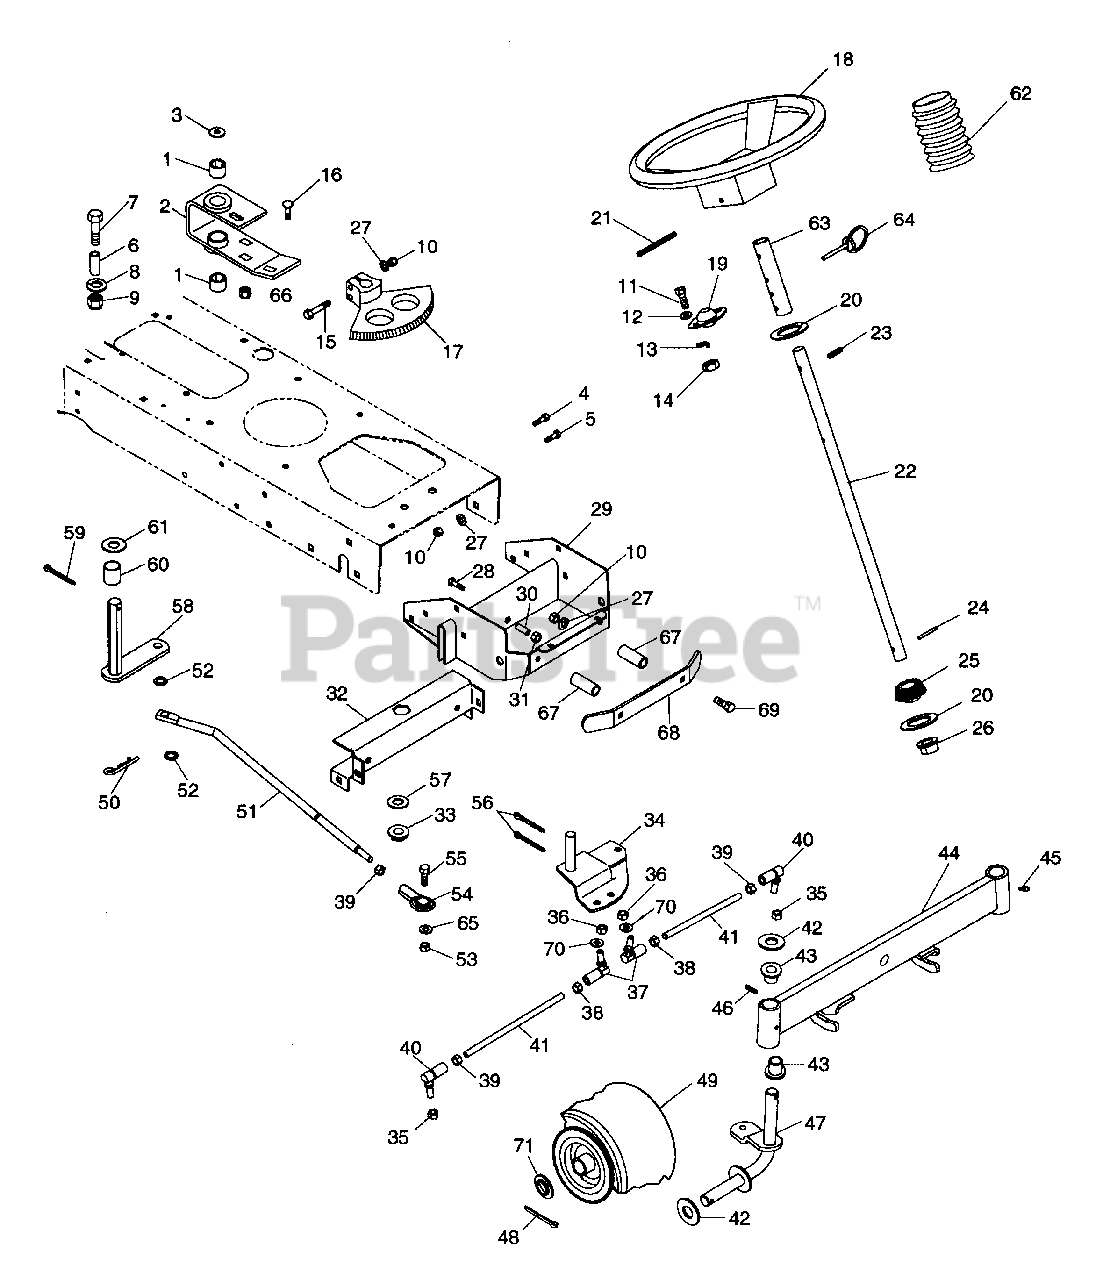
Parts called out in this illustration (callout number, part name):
1	BSHG-SLV .750X1.000X.750 HX SB
2	STEERING BRACKET
3	WSHR-FL-STL .880X1.250X.062
4	BLT-RDHDSQSHNK .38-16X1.00 PL
5	BLT-RDHDSQNK .38-16X.75 SHT PL
6	SPACER .344X.500X.875
7	BLT-HEX .31-18X1.50 PL GR2
8	WSHR-LK .312X.097 PL HVY
9	NUT-HEX .312-18
10	NUT-HEX .375-16
11	BLT-HEX .31-18X.75 PL GR5
12	WSHR-FL-STL.312X.734X.065PL
13	WSHR-LK .312X.097 PL HVY
14	NUT-HEX .312-18
15	BLT-HEX .31-18X1.75 PL GR2
16	BLT-RDHDSQSHNK .38-16X1.00 PL
17	STEERING BEVEL GEAR
18	STEERING WHEEL 13"
19	BRG-FLG .751X2 HOLESX.81
20	WSHR-FL-STL .754X1.125X.062 PL
21	PIN-ROLL .250X1.75
22	STEERING COLUMN
23	PIN-ROLL .188X1.13
24	PIN .249X1.125 DRIV-LOK SP
25	PINION GEAR-STEERING
26	BSHG-FLG .750X1.093X.625X1.375
27	WSHR-LK .375X.094 MED PL
28	BLT-HEX .50-13X1.50 PL GR5
29	FRONT AXLE SUPPORT
30	SPACER .531X.748X.524
31	NUT-LK-CROWN .50-13 GR C PL
32	STEERING PIVOT CHANNEL
33	FLANGE BUSHING
34	STEERING PIVOT
35	NUT-LK .375-24 PL
36	NUT-LK-CTR .375-24
37	BALL JOINT-LH
38	NUT L.H. THD .375-24 PL
39	NUT .375-24 PL
40	BALL JOINT-RH
41	TIE ROD
42	WSHR-FL-STL .755X1.375X.062 PL
43	BSHG-FLG .750X1.000X.750X1.250
44	FRONT AXLE
45	SPIN DRIVE ZERK FITTING
46	PIN-ROLL .250X1.25
47	SPINDLE LH
47	SPINDLE RH
48	PIN-COTR .18X1.25 PL
49	T/WHL ASSY 15X6.00
49	RIM- COMPOSITE 4.5 X 1.75
49	BUSHING- 3/4 BORE- COMP. RIMS
49	T/WHL ASSY 15X6.00-6
49	RIM
49	BSHG .75 BORE
50	PIN-HAIR INT .08X.38X1.42 YWZC
51	DRAG LINK
52	WSHR-FL-STL .520X.827X.062 YZ
53	NUT-LK TOP .375-16 GR C YWZC
54	ROD END, .38 RH
55	BLT-HEX .38-16X1.25 PL GR5
56	PIN-COTR .12 X 1.25 PL
57	WSHR-FL-STL.656X1.312X.095 PL
58	ARM & SHAFT
59	PIN-COTR .18X1.25 PL
60	SPACER .900X1.017X1.090
61	WSHR-FL-STL .875X1.250X.075
63	TUBE .754 X .999 X 5.00
64	PIN-DET W/RING .25X1.00
65	WSHR-FL-STL .382X.812X.062
66	NUT-LK-CTR .375-16 GR A PL
67	SPACER .512X.748X2.50
68	FRONT BUMPER
69	BLT-RDHDSQNK .38-16X3.50 GR5PL
70	WSHR-FL-STL .390X.750X.125 PL
71	SPINDLE WASHER
